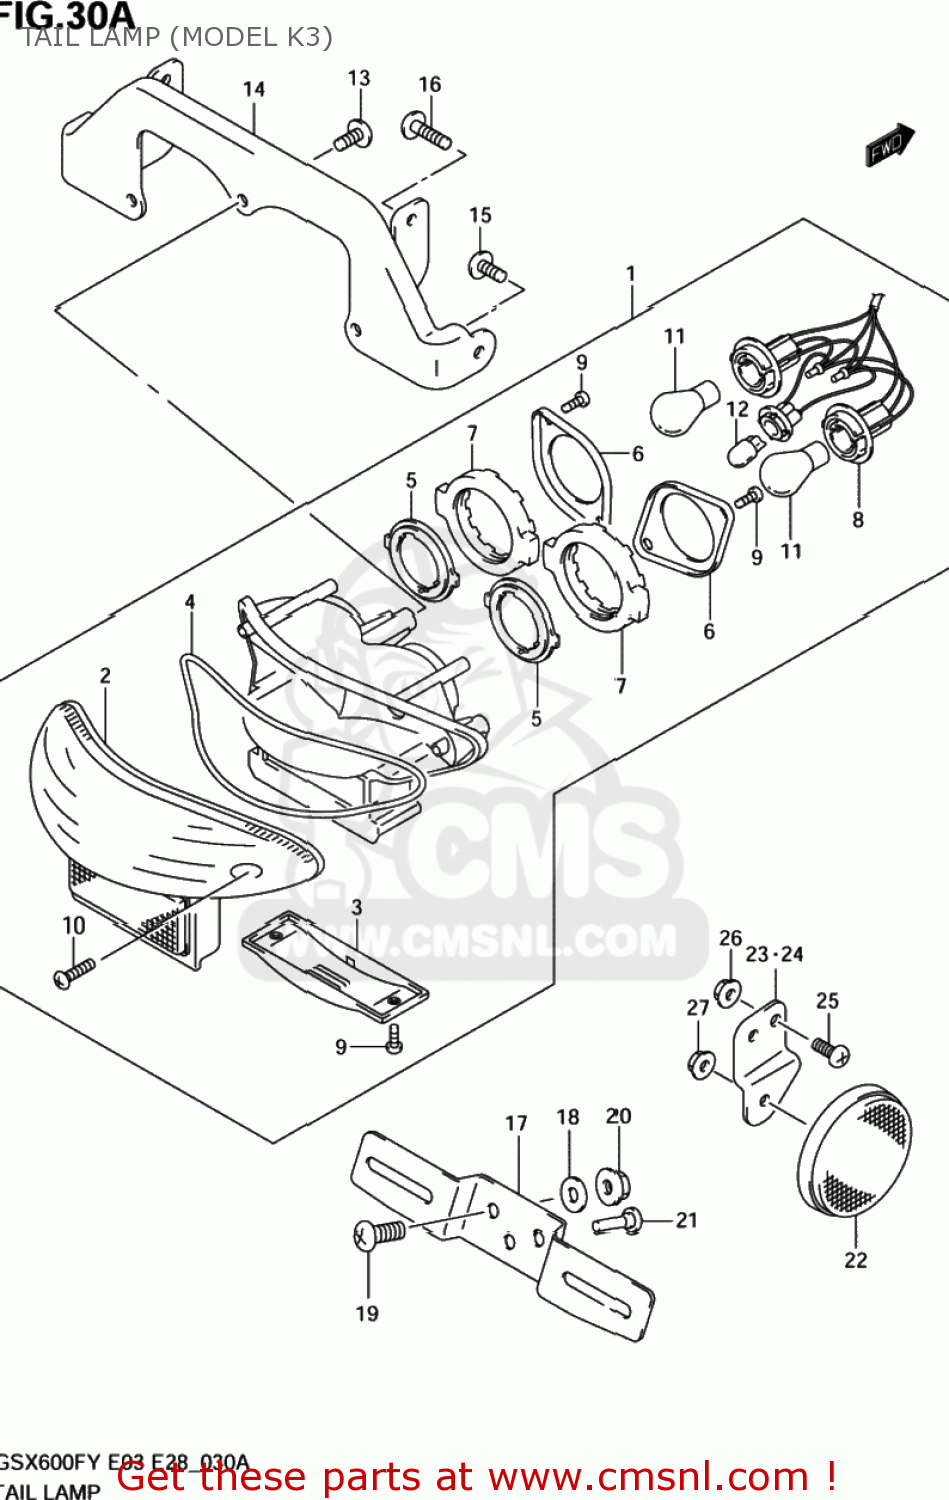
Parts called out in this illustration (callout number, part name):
1	LAMP ASSY,RR COMBINATION
2	LENS
3	LENS,LICENSE LAMP
4	GASKET (NAS)
5	PLATE NO.1
6	PLATE NO.2
7	CUSHION
8	SOCKET & CORD
9	SCREW
10	SCREW
11	BULB(12V21/5W)
12	BULB(12V5W)
13	SCREW
14	BRACKET,RR COMBINATION LAMP
15	SCREW
16	SCREW
17	BRACKET,LICENSE PLATE
18	WASHER(6.5X20X1.6)
19	SCREW
20	NUT
21	CUSHION
22	REFLECTOR ASSY,RR SIDE
23	BRACKET,RR SIDE RR,R
24	BRACKET,RR SIDE RR,L
25	SCREW
26	NUT
27	NUT
